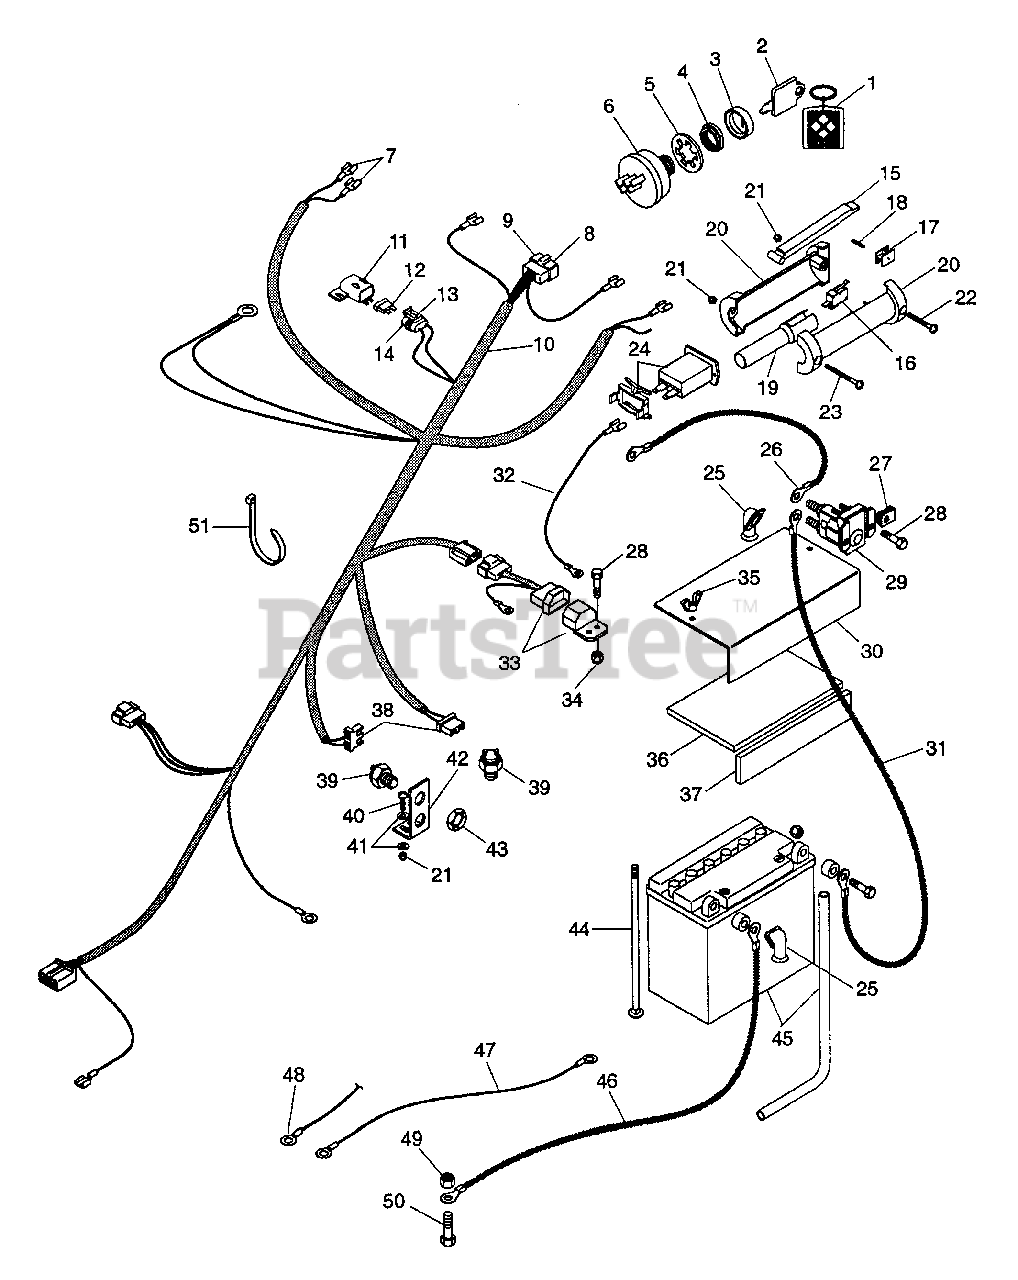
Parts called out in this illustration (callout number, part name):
1	Key Chain
2	Ignition Switch Key
3	Cap, Ignition Switch
4	Nut-Panel .625-32
5	Washer-Lock .625
6	Switch, Ignition w/Ground
7	Terminal, Female
8	Terminal
9	Connector
10	Harness, Wiring 18 Kohler
10	Wire Harness, Pro-200
12	Fuse, 25 AMP
13	Terminal, For 14-16 Ga Wire
14	Assembly, Connector Weather Tight
17	Holder, Switch
18	Pin-Roll .094 x .750
19	Insert, Handlebar
20	Handle, Left Hand and Right Hand
21	Nut-Locking 10-24
22	Screw-Machine 10-24 x .625
23	Screw-Machine 10-24 x 1.50
24	Hour Meter
25	Boot, Insulator
26	Cable, Solenoid to Starter
26	Cable, Starter
27	Nut-Speed .25-20
28	Bolt-Hex .25-20 x .75 Grade 5
29	Solenoid
30	Cover, Battery
31	Cable, Battery to Solenoid
32	Wire, Instrument Panel
33	Kit, Interlock Module, Electric
33	Adapter Harness, Interlock
33	Module, Interlock, Electric
34	Nut-Locking-Nylon .250-20 Grade 2
35	Nut-Wing .250-20
36	Pad, Battery
37	Pad, Battery
38	Connector, 2-Wire Switch
39	Switch-Neutral Start N.C.
40	Screw-Machine 10-24 x .750
41	Washer-Flat-Steel .188 x .438 x .049
42	Bracket-Interlock Switch
43	Nut-Stamped .56-18
44	Bolt-Round Head Square Neck .25-20 x 7.00
45	Battery, 12 Volt
46	Cable, Negative Battery
47	Wire, Ground
48	Terminal, Ring Tongue
49	Nut-Locking- Nylon .312-18 Grade 2
50	Bolt-Hex .31-18 x 2.25 Grade 5
51	Tie Wrap, Black
